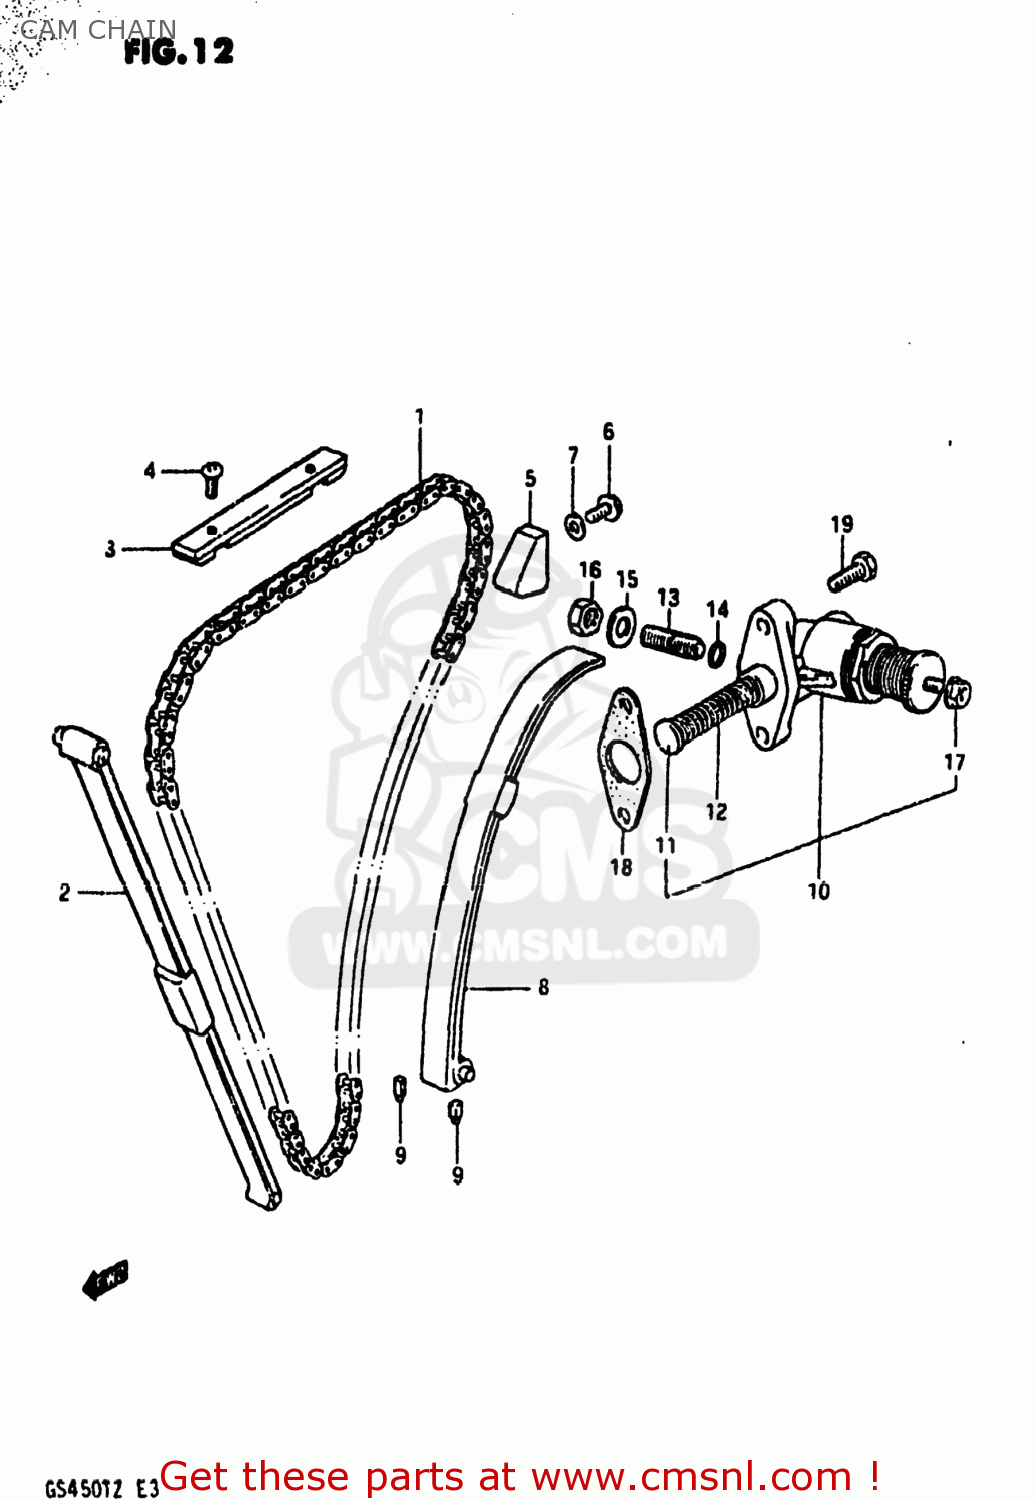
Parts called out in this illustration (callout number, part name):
1	CHAIN,CAMSHAFT DRIVE(120L)
2	GUIDE,CAM CHAIN NO.1
3	GUIDE,CAM CHAIN NO.3
4	SCREW
5	GUIDE,CAM CHAIN
6	BOLT
7	GASKET (NAS)
8	TENSIONER,CAM CHAIN
9	CUSHION,CAM CHAIN TENSIONER
10	ADJUSTER ASSEMBLY,TENSIONER
11	ROD,PUSH
12	SPRING
13	SCREW
14	O-RING
15	WASHER
16	NUT
17	NUT
18	GASKET,TENSIONER ADJUSTER (MCA)
19	SCREW (6X25)
